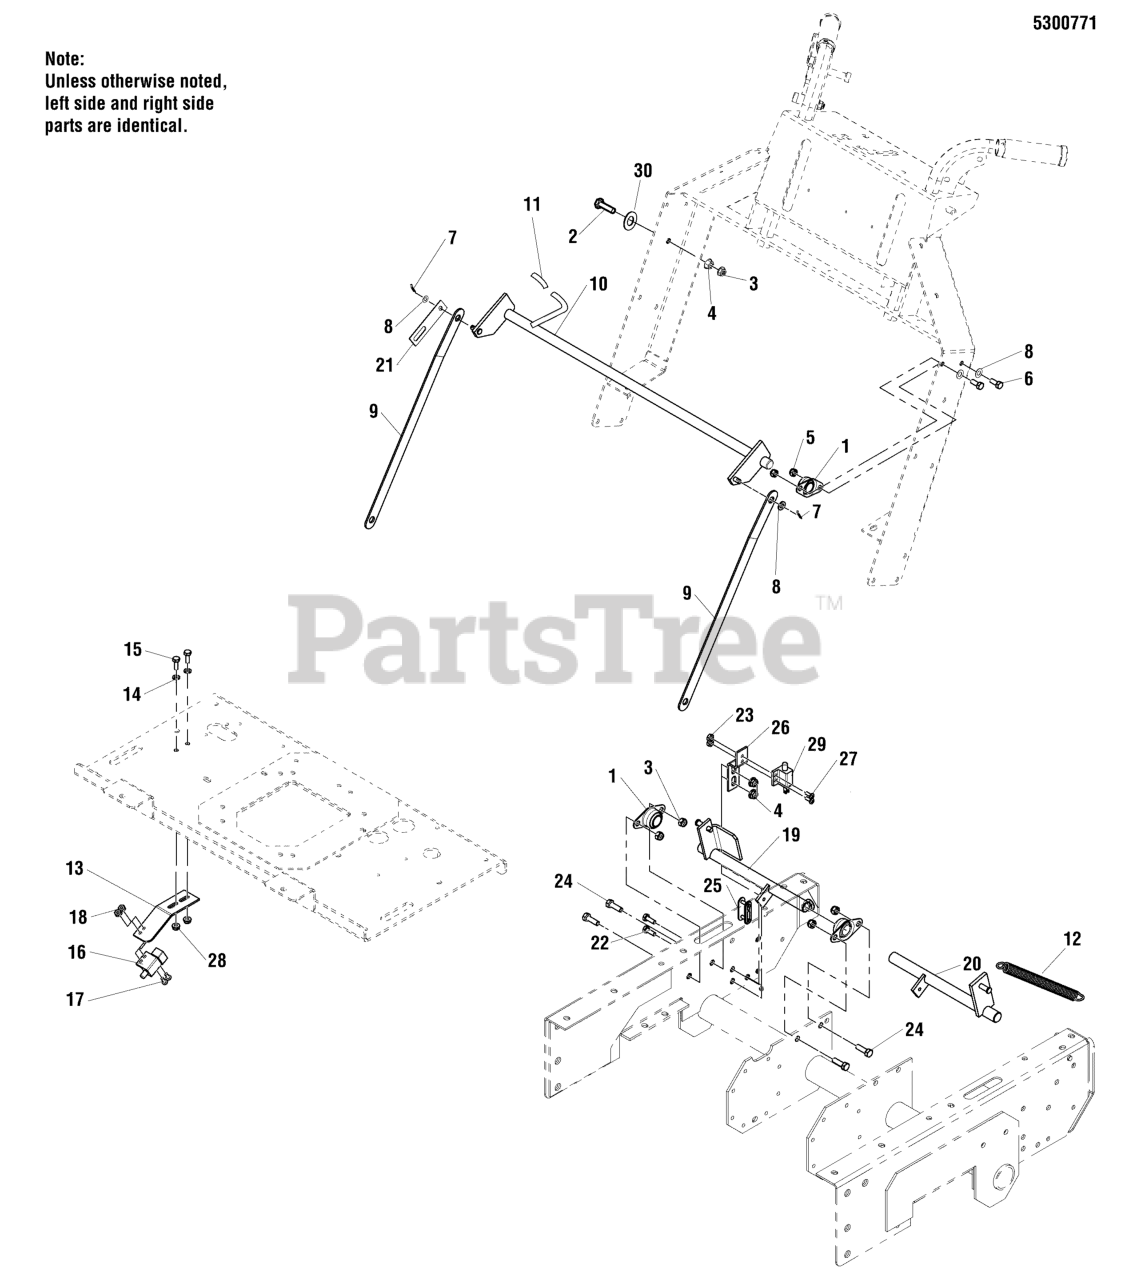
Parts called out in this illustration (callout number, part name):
1	BEARING, BRONZE FLANGE 3/4"
2	BOLT, 3/8-16 X 1-1/2" GD5 CZ
3	NUT, 3/8-16 HEX NYLOCK FLANGE
4	NUT, 3/8-16 HEX LG. SERR FLG
5	NUT 5/16-18 HEX NYLON LOCK
6	BOLT, 5/16-18 X 3/4 GD5
7	PIN, 3/32 X 0.750, COT, ZINC/CLEAR
8	WASHER, 5/16" SAE
10	WELD, BRAKE LEVER
11	GRIP, FOAM
12	SPRING-EXT, .750OD X 7.65LG X .115WR
13	MOUNT, SWITCH
14	WASHER, 1/4 SAE
15	BOLT, 1/4-20 X 3/4 GD5
16	SWITCH, BLACK PLUNGER
17	SCREW, #10-24 X 1/2" ROUND PHILLIPS
18	NUT, #10-24 HEX
19	WELD, BRAKE SHAFT, RH
20	WELD, BRAKE SHAFT, LH
21	PLATE, BRAKE STOP
22	BOLT, 3/8-16 X 3/4" GD5 CZ
23	NUT, HEX, #10-24
24	BOLT, 3/8-16 X 1" GD5 CZ
25	LINK, #A20/50 CONNECTING
26	MOUNT, DDS NEUTRAL SWITCH
27	SCREW, #10-24 X 1/2" ROUND PHILLIPS
28	NUT, 1/4-20 HEX SERR. FLANGE
29	SWITCH, PLUNGER, N.O./N.C.
30	WASHER, 3/8 SAE
